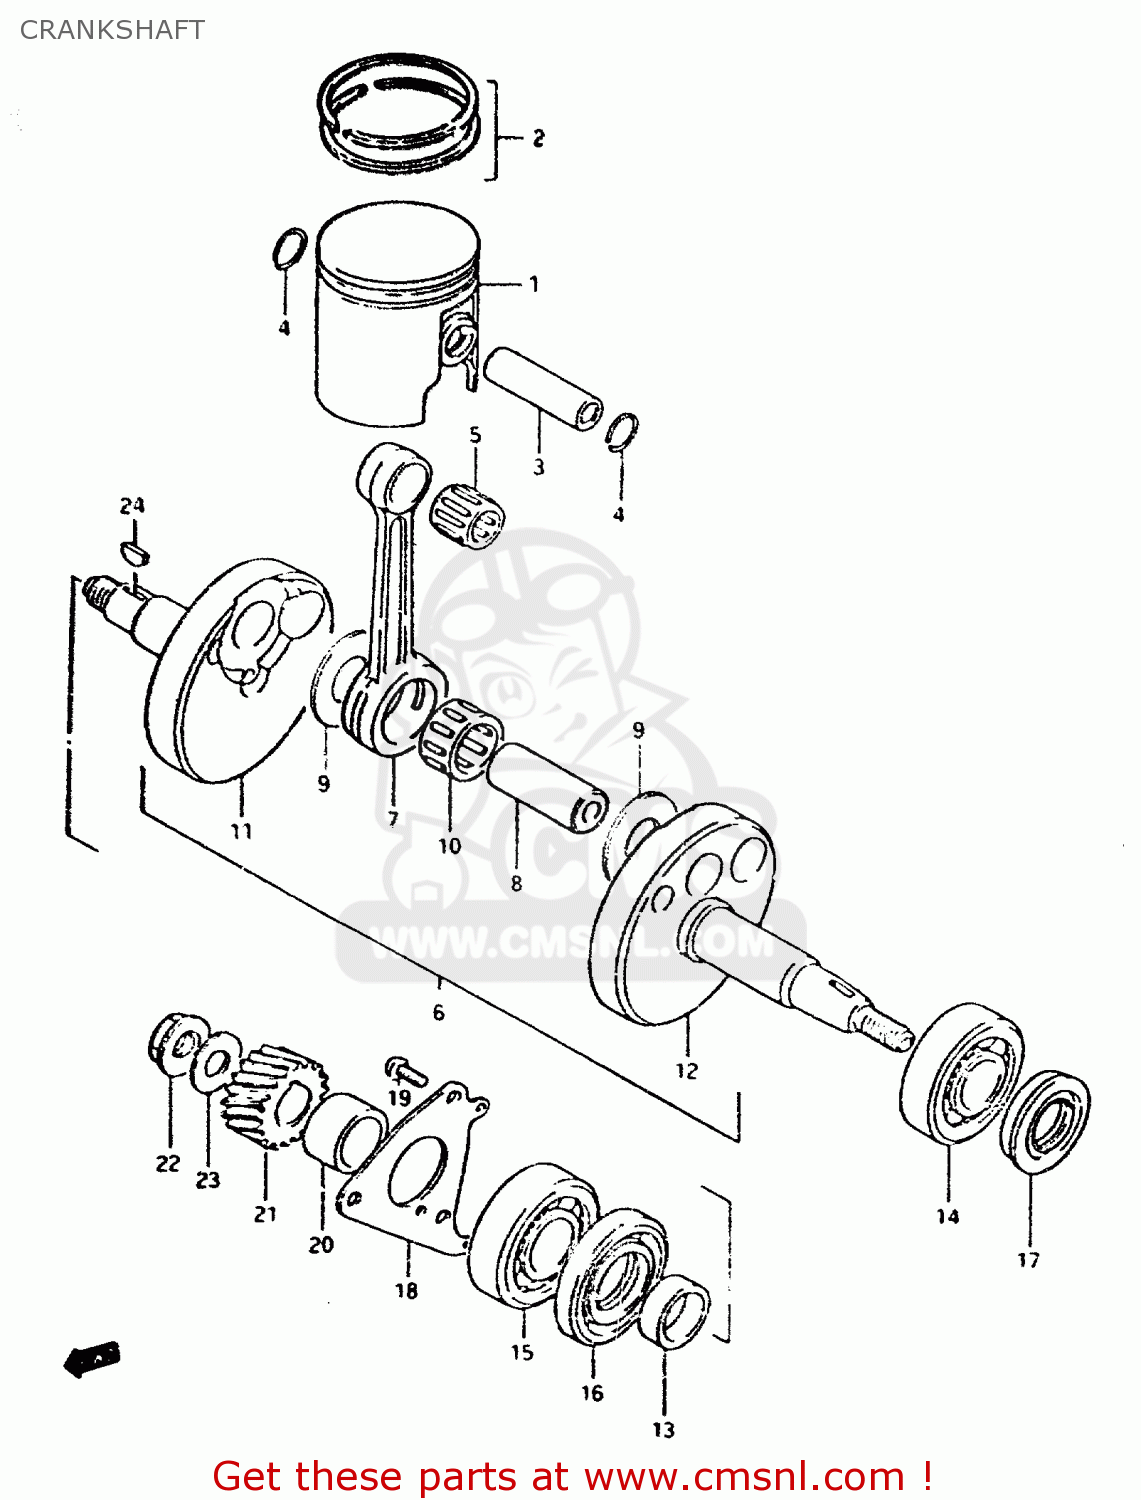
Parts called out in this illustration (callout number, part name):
1	PISTON
2	RING SET,PISTON
3	PIN,PISTON
4	RING,SNAP
5	BEARING
6	CRANKSHAFT ASSEMBLY
7	CONNECTING ROD
8	PIN,CRANK
9	WASHER(16X29X1)
10	BEARING
11	CRANKSHAFT
12	CRANKSHAFT,LEFT
13	SPACER(20X26X9)
14	BEARING(20X47X14)
15	BEARING
16	SEAL,OIL(26X47X7.3)
17	SEAL,OIL(19.6X37X8)
18	RETAINER,CRANKSHAFT BEARING,R
19	SCREW 6X12
20	SPACER(20X26X14)
21	GEAR,PRIMARY DRIVE NO.19
22	NUT
23	WASHER
24	KEY
